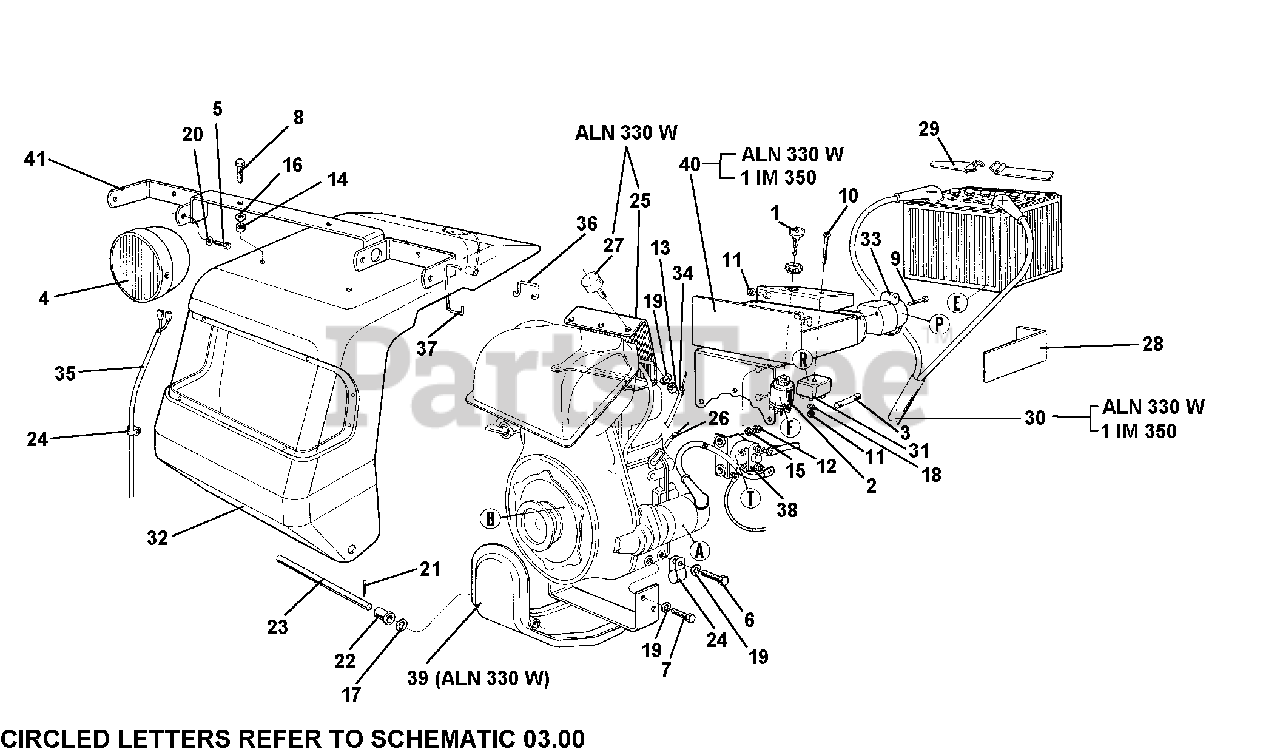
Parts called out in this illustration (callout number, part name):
3	FUSE 6 X 25 25A
5	SCREW TE M6 X 14
6	SCREW TE M8 X 12
7	SCREW M8 X 16
8	SCREW M8 X 25
9	SCREW TCCEI M4 X 30
10	SCREW TC M4 X 30 UNI 6107
14	NUT, SELF LOCKING M8
15	WASHER, FLAT 6.4
16	FLAT WASHER 9 X 24 UNI 6593
17	FLAT WASHER 10.5 X 21
18	LOCK WASHER B 4.3
19	WASHER, LOCK 8.4
20	WASHER, LOCK AZ 6.4 DIN 6798
21	PIN, COTTER A 3 X 20 UNI 1336
23	PIN, COUPLING
24	CLAMP ENGINE
25	CONNECT. UPPER ELECTRIC ST.
26	CABLE & SHEATH, ACCEL.LOMBAR
28	ANTISHOCK BAT
29	BATTERY STRAP
30	ELECTRIC START CABLES MC 715
32	HOOD, PLASTIC, COMPLETE
33	7-POLE SOCKET
34	SHEATH CABLE
35	COVER CABLES
36	ELECTRIC STARTER HOOK
38	BOSCH RELAY 0332002160
39	HOOD LOWER COUPLING
40	BATT. SUPPORT COMPL.
41	LIGHT SUPPORT
